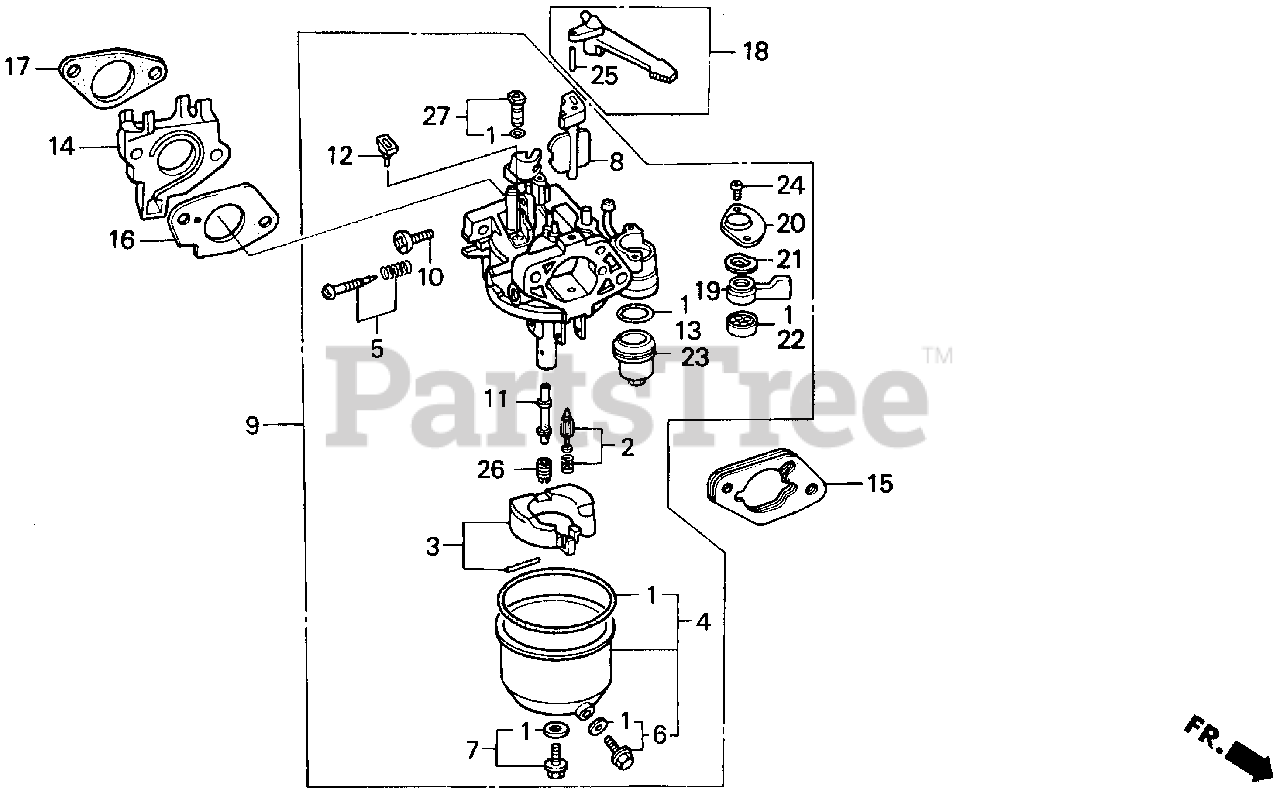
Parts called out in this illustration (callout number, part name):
1	GASKET SET
2	VALVE SET, FLOAT
3	FLOAT SET
4	CHAMBER SET, FLOAT
5	SCREW SET, PILOT
5	SCREW SET
6	SCREW SET, DRAIN
7	SCREW SET B
8	CHOKE SET
9	CARBURETOR ASSY. (BE80C A)
9	CARBURETOR ASSY. (BE47A B)
10	SCREW, THROTTLE STOP
11	NOZZLE, MAIN
12	COLLAR, SET
13	GASKET, FUEL STRAINER CUP
14	INSULATOR, CARBURETOR
15	SPACER, CARBURETOR
16	GASKET, CARBURETOR
17	GASKET, INSULATOR
18	LEVER, CHOKE (STD)
19	LEVER, VALVE
20	PLATE, LEVER SETTING
21	SPRING, VALVE LEVER
22	GASKET, VALVE
23	CUP, FUEL STRAINER
24	SCREW, PAN (3X6)
24	SCREW, PAN (3X8)
25	PIN, SPRING (2X12)
26	JET, MAIN (#95)
26	JET, MAIN (#98)
26	JET, MAIN (#100)
26	JET, MAIN (#102)
26	JET, MAIN (#105)
26	JET, MAIN (#108)
27	JET SET, PILOT (#40)
27	JET SET, PILOT (#35)
